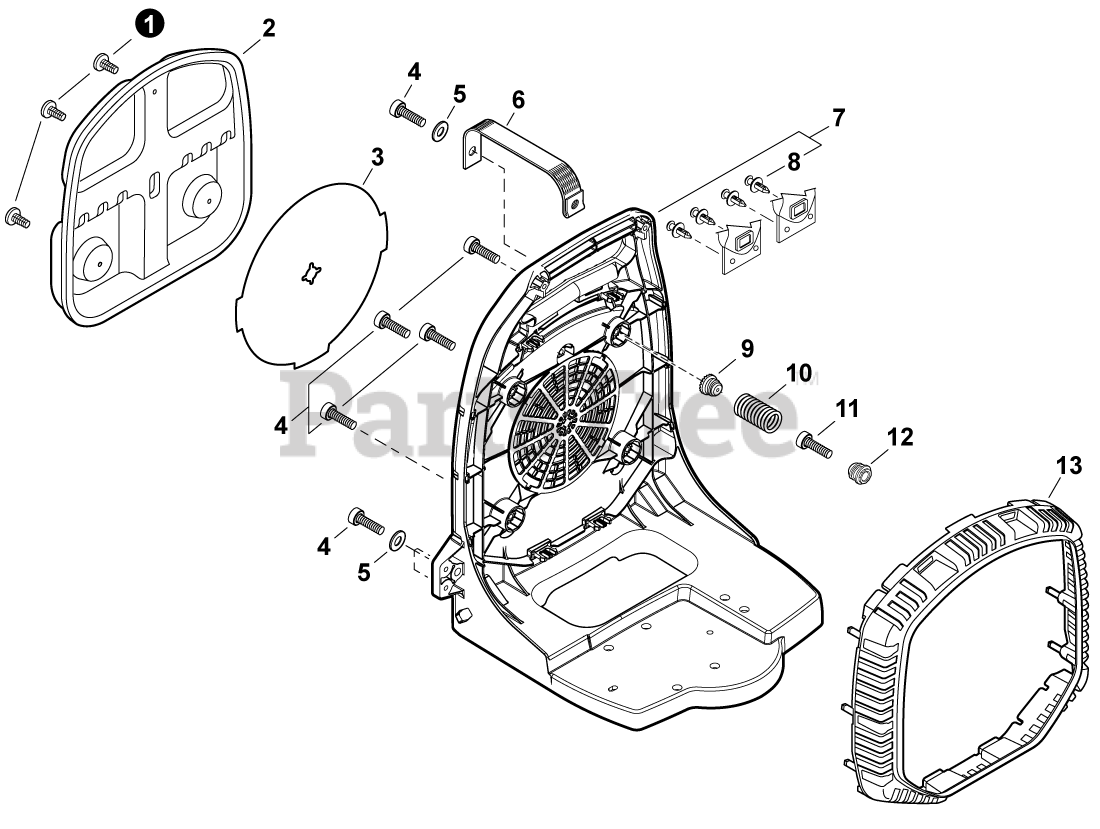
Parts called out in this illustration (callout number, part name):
2	CUSHION, BACKPACK
3	INSERT, COLD WEATHER
4	BOLT, TORX 5×20
5	WASHER 5.5×16×2T
6	STRAP, SAFETY 1.2×100
7	FRAME, BACKPACK WITH CLIPS
9	HOLDER, SPRING
10	SPRING, COMPRESSION
11	BOLT, TORX 5×16
12	HOLDER, SPRING
13	GUARD, DEBRIS
